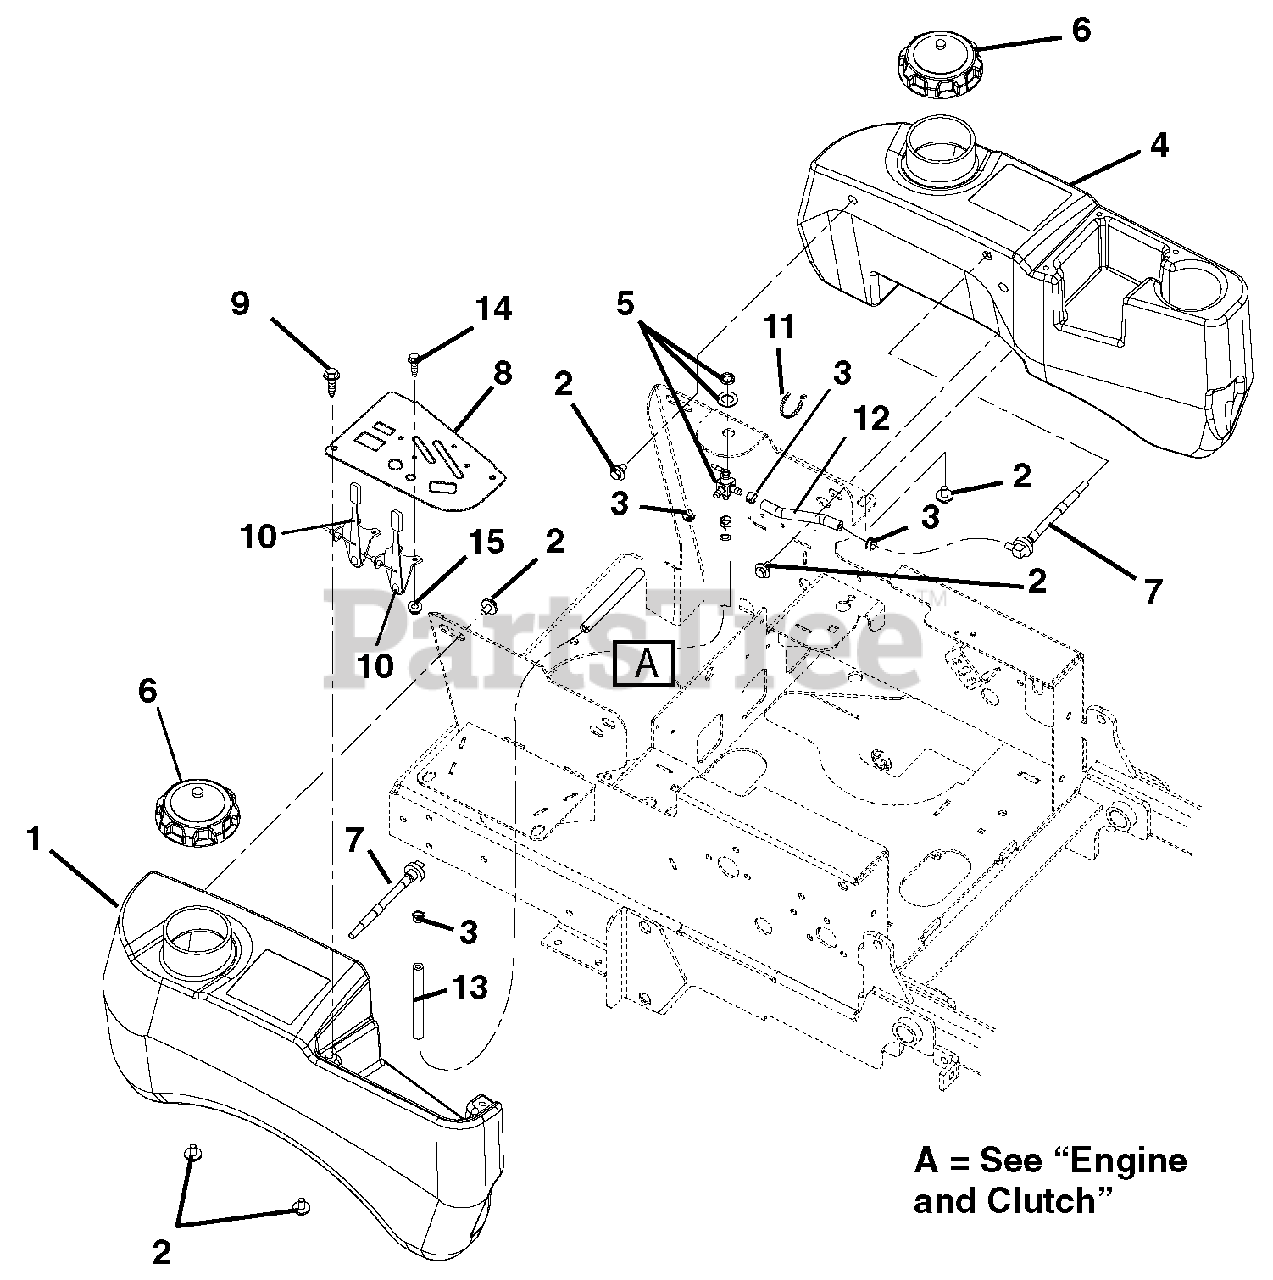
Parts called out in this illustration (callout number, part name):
1	TANK, FUEL RH W/O HOSE
2	BOLT, SEMS .31-18 X .62
3	CLAMP, FUEL LINE
4	TANK, LH FUEL CZ W/O HOSE
5	VALVE, FUEL
6	CAP, FUEL
7	ASS'Y, SMALL TANK FUEL PICK-UP
8	PANEL - CONTROL
9	SCR-MCH 10-24X.38 HWHSTAINLESS
10	CABLE, CONTROL
11	CABLE TIE LG 5-1/2
12	HOSE, .25 LOW-PERM BULK GAS
13	HOSE, .25 LOW-PERM BULK GAS
14	@SCR-MCH 10-24X.50 HWH YWZC
15	@NUT-LK-NYL 10-24 W/INSRT YWZC
